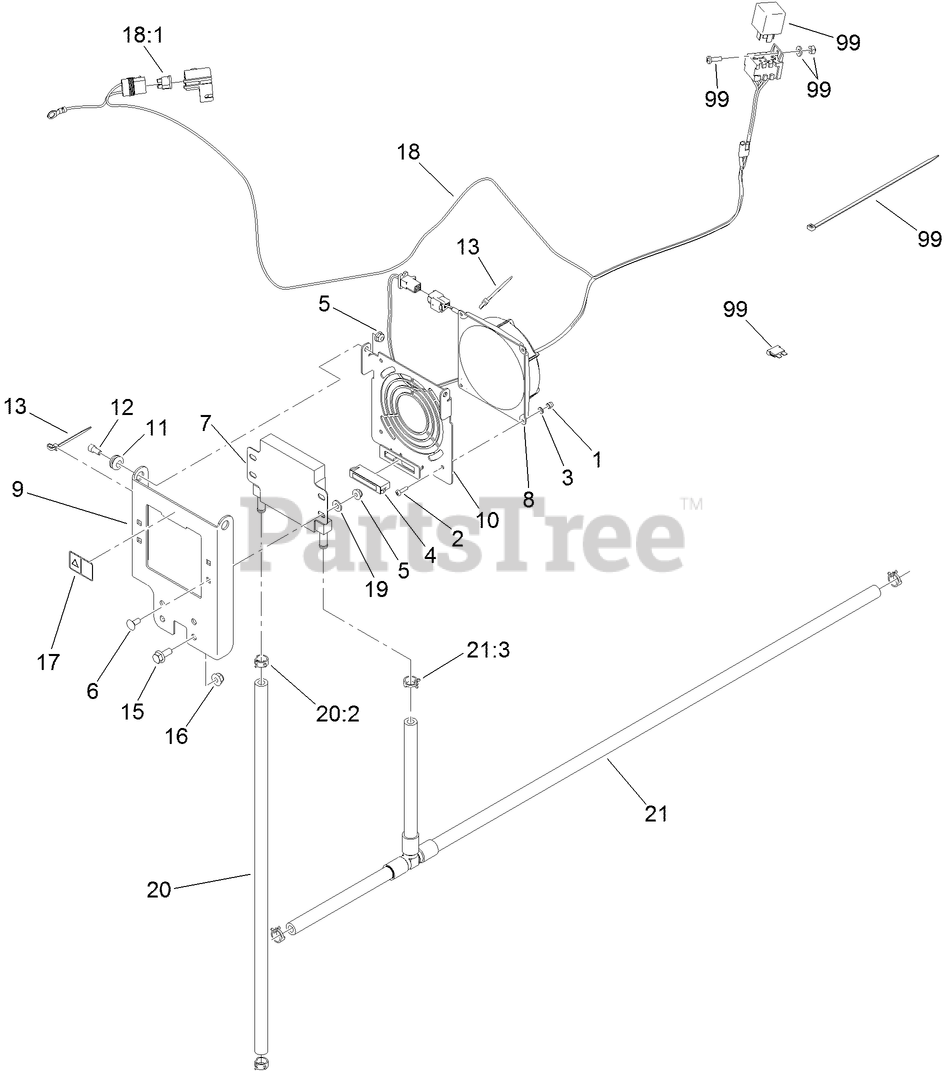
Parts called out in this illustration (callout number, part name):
1	NUT-LOCK
2	SCREW-PPH
3	WASHER-FLAT
4	CATCH-MAGNETIC
5	NUT-HF
6	SCREW-CARR
7	COOLER-OIL
8	FAN-ELECTRIC
9	BRACKET-MOUNT, FAN
10	BRACKET-MOUNT, FAN
11	GROMMET
12	SCREW-HSH
13	TIE-CABLE
15	SCREW-HHF
16	NUT-HF, NI
17	DECAL-WARNING
18	HARNESS-WIRE
18:1	FUSE-BLADE, 10 AMP
19	WASHER-FLAT
20	HOSE ASM
20:2	CLAMP-HOSE
21	TANK HOSE ASM
21:3	CLAMP-HOSE
99	FUSE-BLADE, 15 AMP
99	TIE-CABLE
99	SCREW-PPH
99	WASHER-FLAT
99	NUT-LOCK, NI
